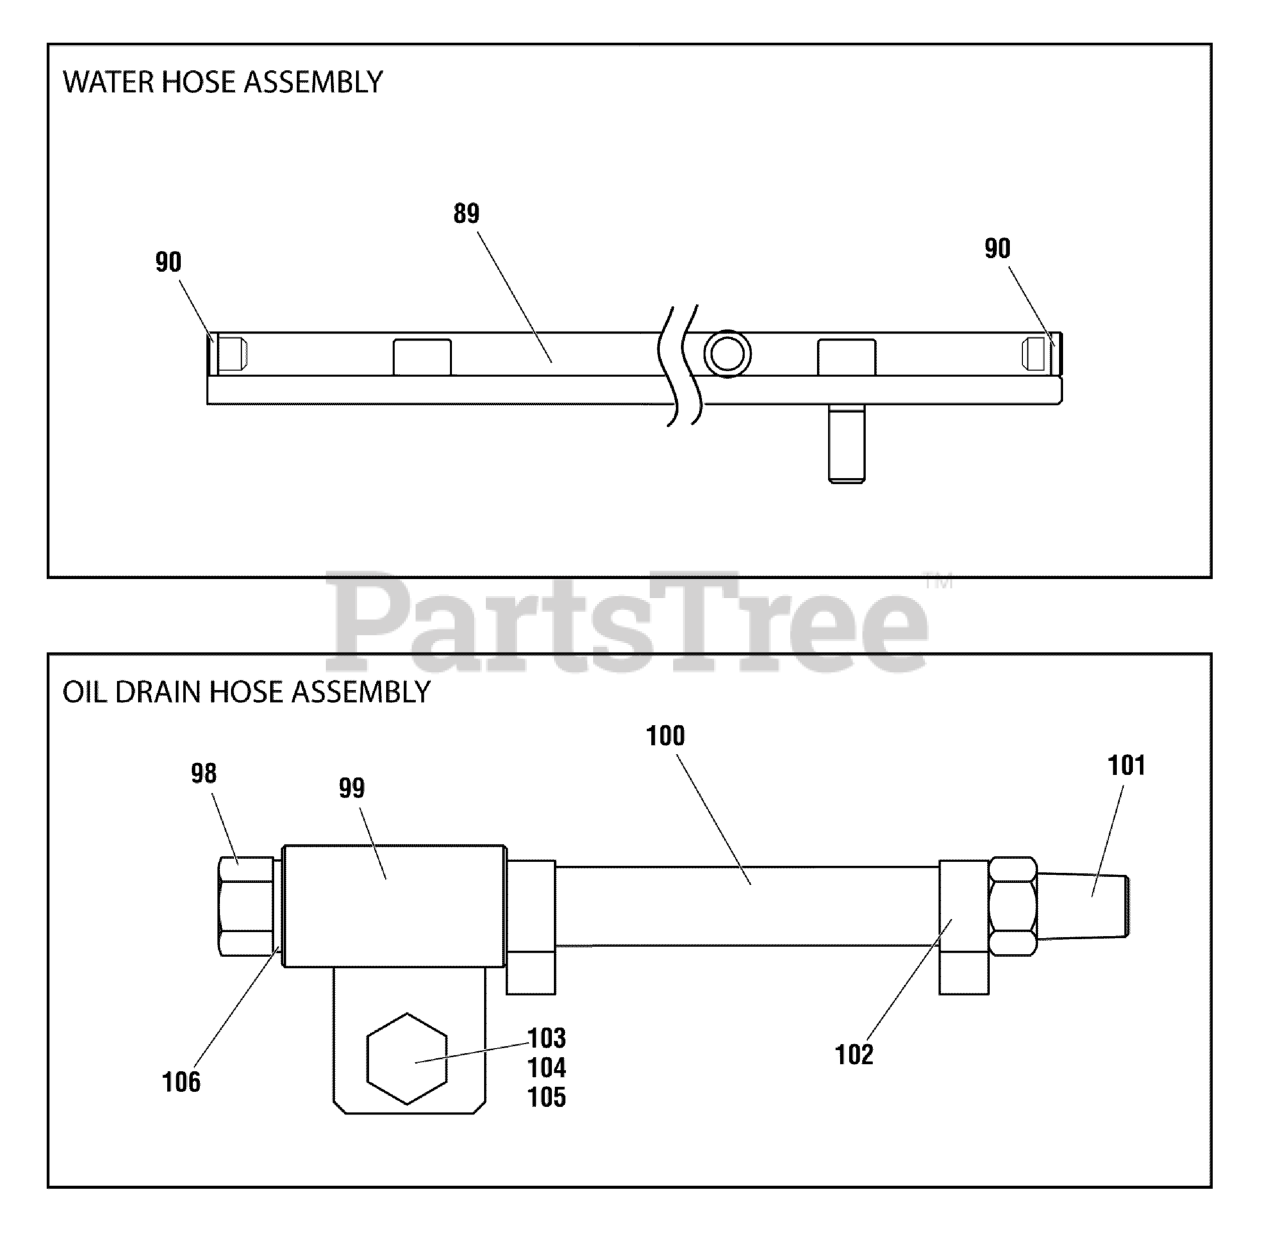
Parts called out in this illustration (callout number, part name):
89	WATER HOSE ASSEMBLY
90	NYLON STOPPER
98	PLUG, Hex Head
99	NOZZLE
101	TAPER JOINT
102	SPRING CLAMP
103	BOLT, Hex Head
104	WASHER, Spring, 8
105	NUT, Hex Lock, M8
106	GASKET, Sealing, 14
